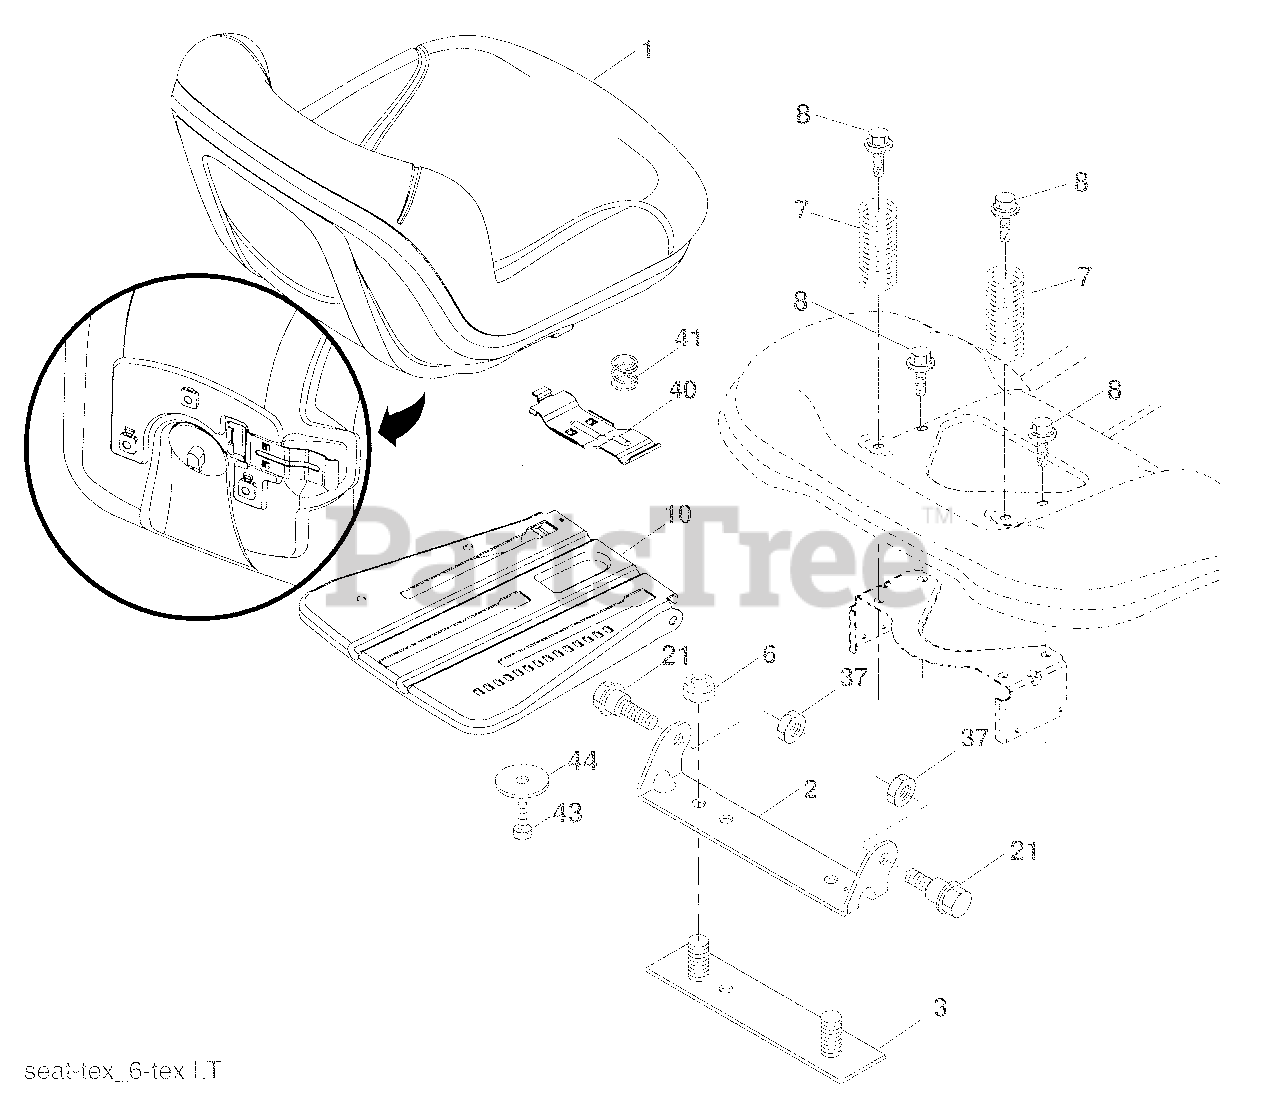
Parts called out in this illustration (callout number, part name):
1	Seat
2	Bracket Pivot Fender
3	Strap, Asm Fender
6	Nut, Lock w/Ins. 3/8-16 unc
7	Spring, Seat Cprsn
8	Bolt 5/16-18 unc x 3/4 w/Sems
10	Pan, Seat
21	Bolt, Shoulder 5/16-18
37	Nut, Lock 5/16-18 unc
40	Handle Slide Seat
41	Spring Latch Seat
43	Bolt Fin Hex 3/8-16 unc x 3/4
44	Washer 13/32 x 2-3/8 x 12 Ga.
